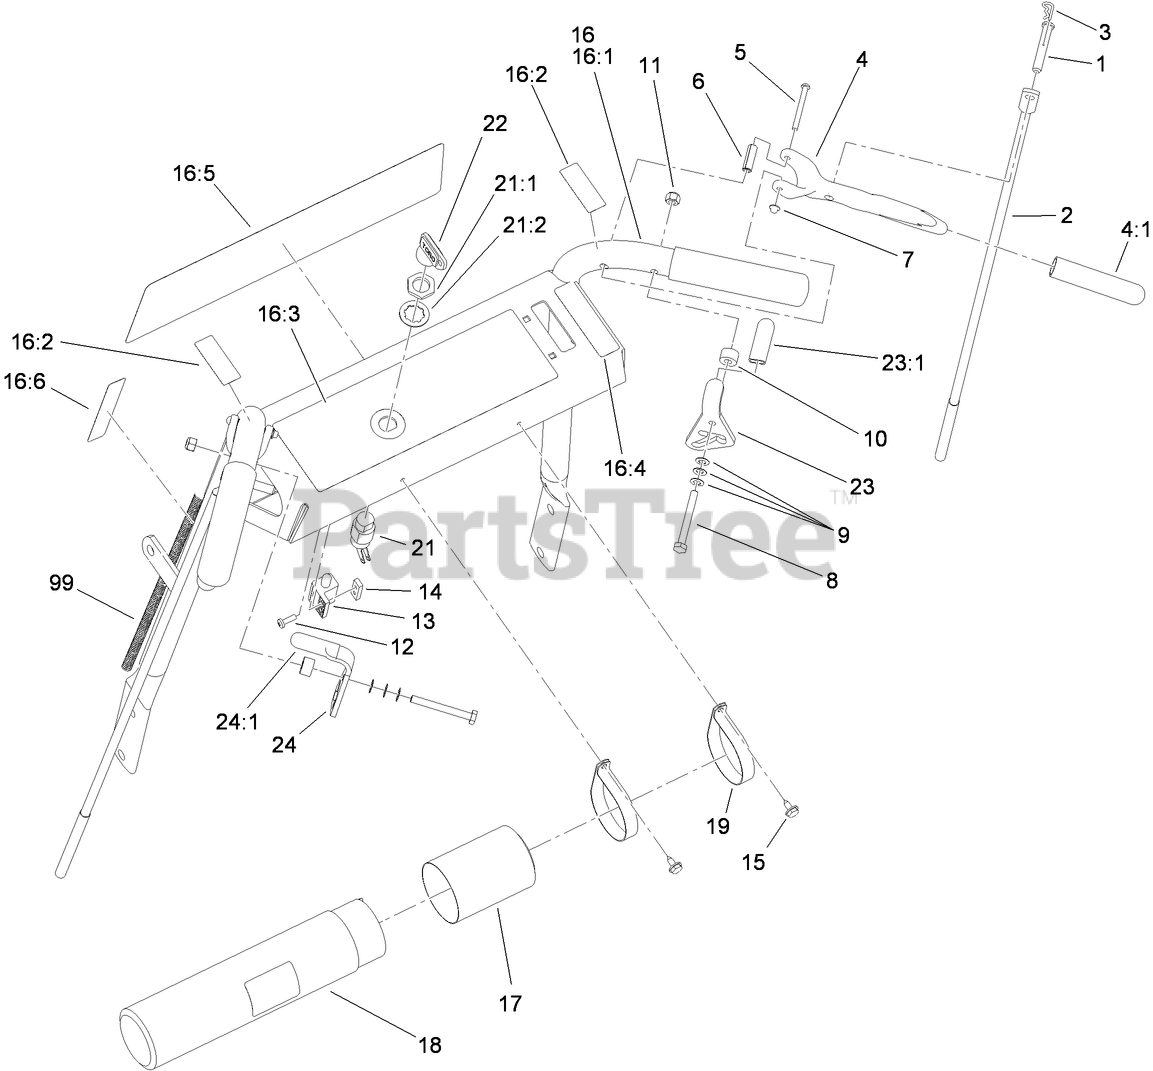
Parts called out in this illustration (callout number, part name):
1	PIN-CLEVIS
2	Linkage-Wheel, Drive
3	PIN-COTTER
4	DRIVE LEVER ASM
4:1	GRIP-LEVER, DRIVE
5	PIN-LEVER, DRIVE
6	PIN-ROLL
8	SCREW-HH
9	WASHER-SPRING
10	SPACER
11	NUT-LOCK, NI
12	SCREW-PPH
13	SWITCH-OPEN, NORMALLY
14	PLATE-TAPPED
15	SCREW-HWHTF
16	HANDLE ASM
16:1	PISTOL GRIP HANDLE ASM
16:2	DECAL-LOCK, NEUTRAL
16:3	DECAL-WARNING
16:4	DECAL-THROTTLE
16:6	DECAL-ENGAGE, DECK
17	CAP-HOUSING
18	TUBE-MANUAL
19	CLAMP-R
21	SWITCH-ON / OFF
21:1	NUT-HH
21:2	WASHER-TOOTH, INTERNAL
22	KEY-IGNITION
23	RH THUMB LATCH ASM
23:1	GRIP-LATCH
24	LH THUMB LATCH ASM
24:1	GRIP-LATCH
99	HARNESS-WIRE
